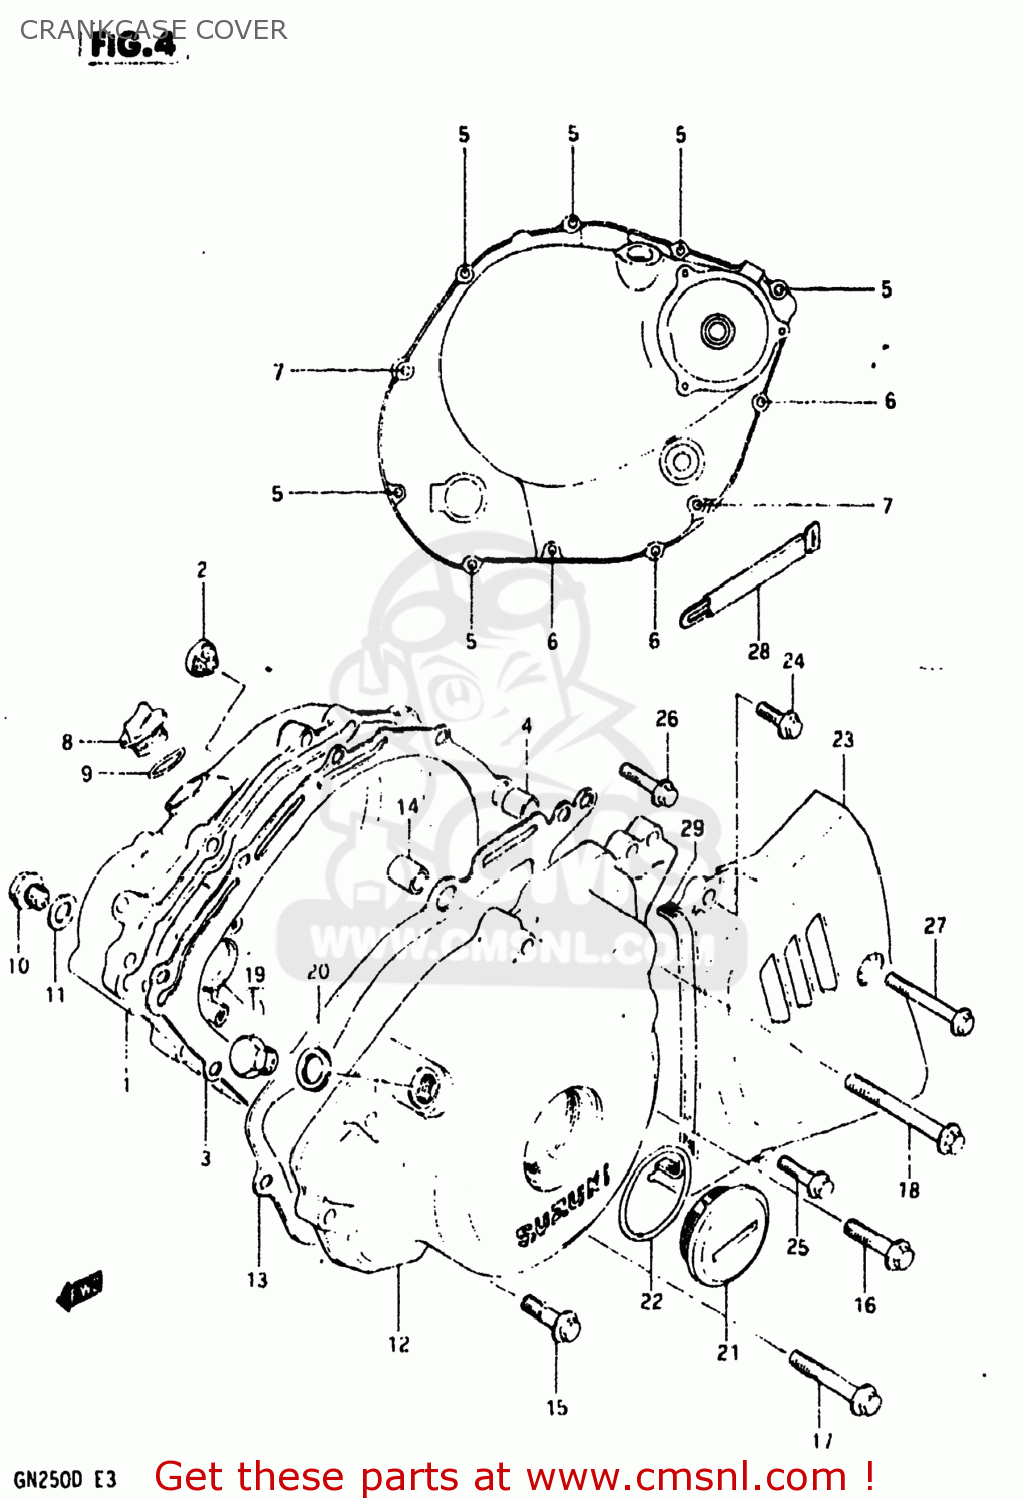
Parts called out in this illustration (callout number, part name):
1	COVER,CLUTCH
2	LENS,OIL LEVEL CHECK
3	GASKET,CLUTCH COVER
4	PIN
5	BOLT
6	BOLT (6X35)
7	BOLT
8	PLUG(20X10)
9	O RING(D:3.1,ID:16.8)
10	PLUG (14X12)
11	GASKET(14X19.2X2) (NAS)
12	COVER,MAGNETO
13	GASKET,MAGNETO COVER (MCA)
14	PIN
15	BOLT
16	BOLT (6X35)
17	BOLT (6X50)
18	BOLT
19	PLUG,12X9
20	GASKET(12.1X16.2X3.7) (NAS)
21	PLUG
22	O RING(D:3.1,ID:32.7)
23	COVER,ENGINE SPROCKET
24	BOLT (5X20)
25	BOLT
26	BOLT (5X30)
27	BOLT
28	CLAMP L:110
29	DAMPER,ENGINE SPROCKET COVER
